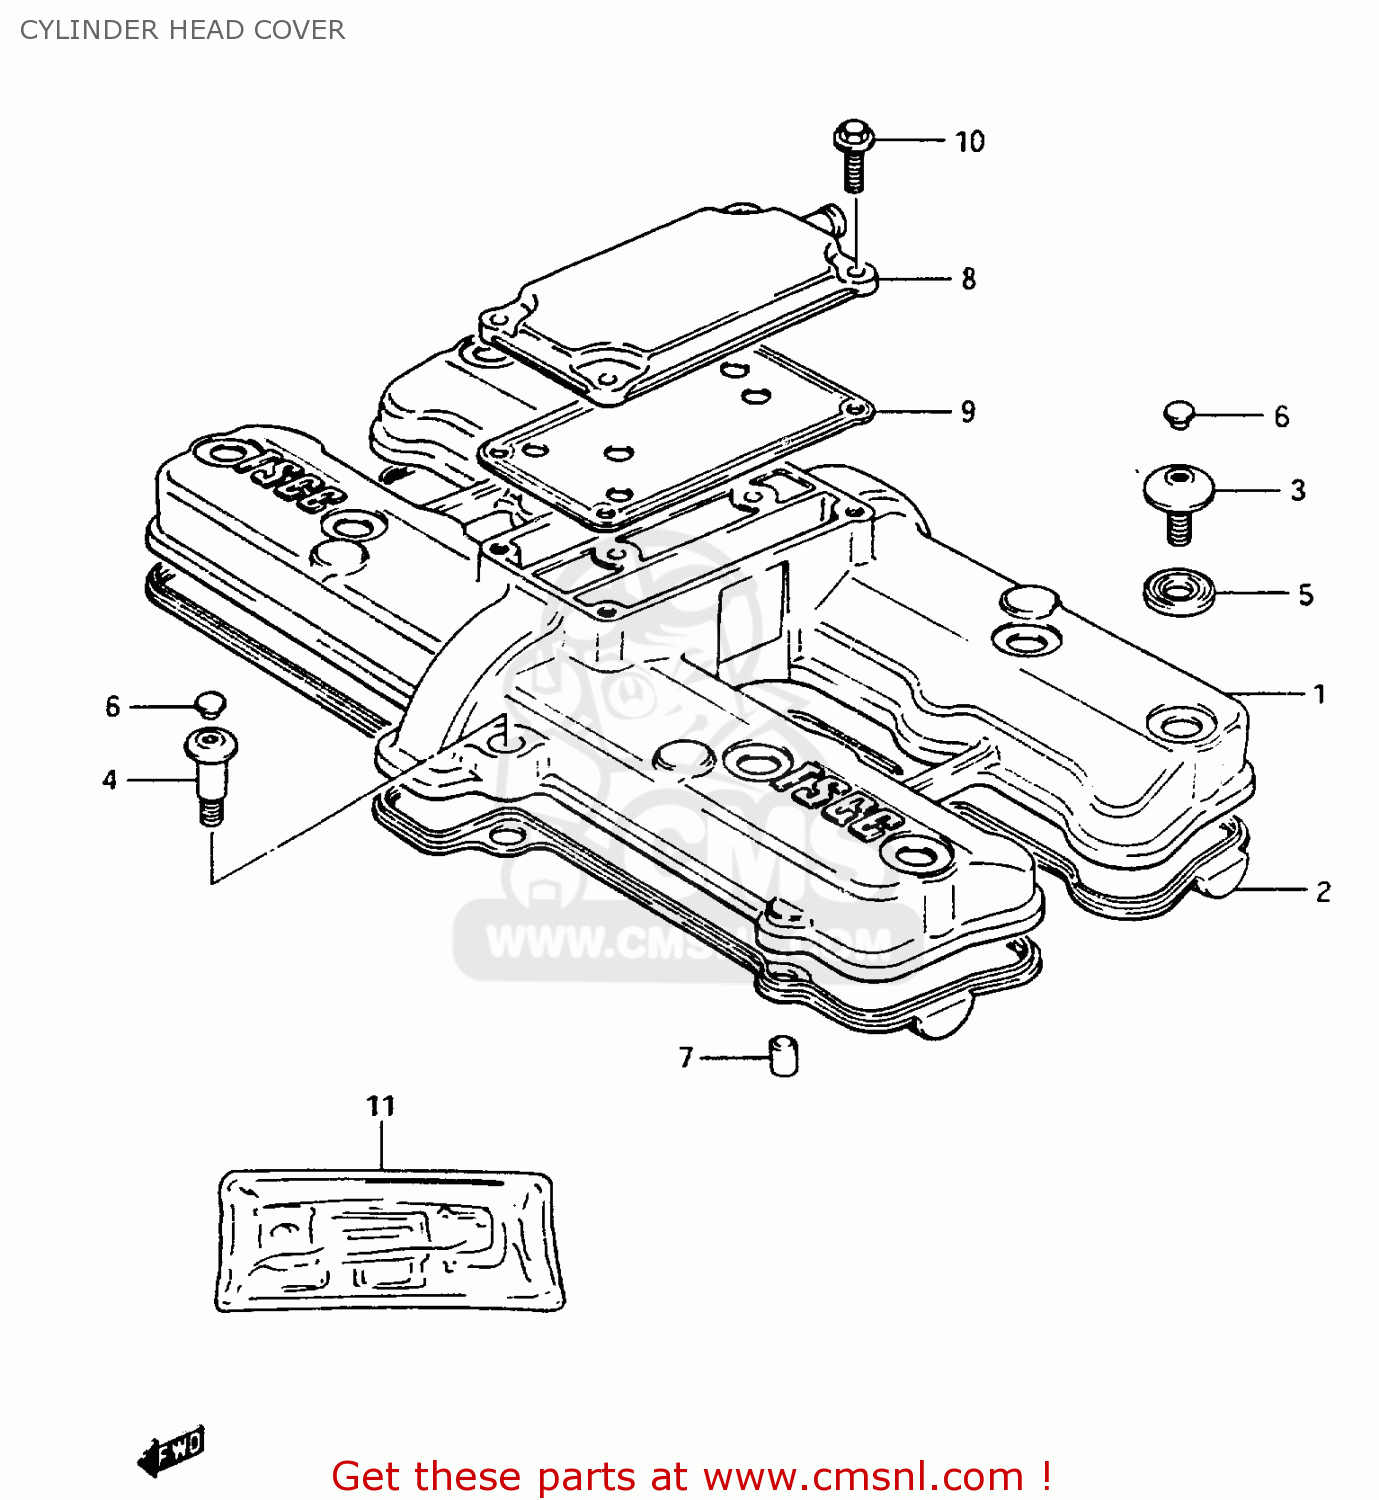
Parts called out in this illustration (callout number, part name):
1	COVER,CYLINDER HEAD
2	GASKET,HEAD COVER (NAS)
3	BOLT(7X5.5)
4	BOLT(7X19)
5	WASHER
6	CAP(OD:10)
7	PIN
8	COVER,BREATHER
9	GASKET (MCA)
10	BOLT,REAR
11	GASKET SET
